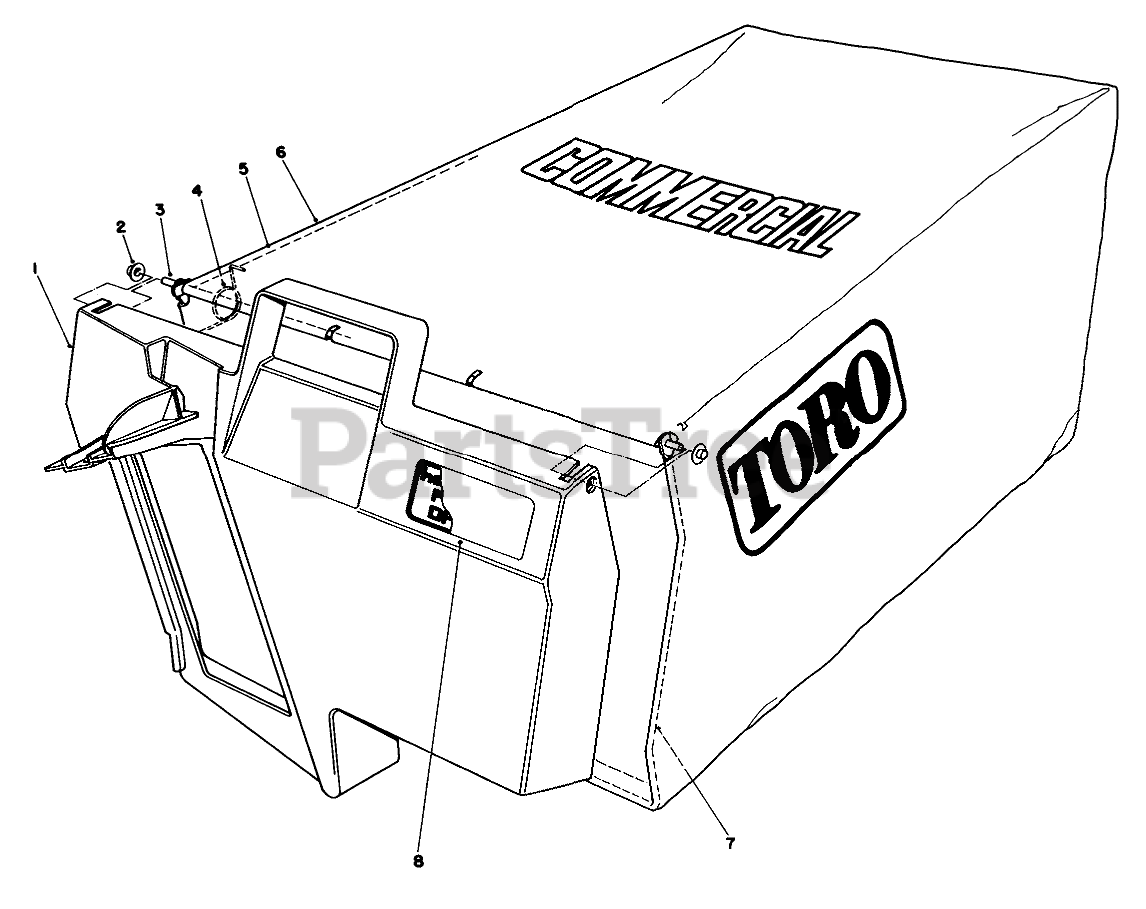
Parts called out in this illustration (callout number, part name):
1	Door-Grass Bag
2	NUT-PUSH
3	HINGE-DOOR, BAG
4	SPRING
5	FRAME-BAG, UPPER
6	Bag-Grass
7	FRAME-BAG
8	Decal-Bag Door
